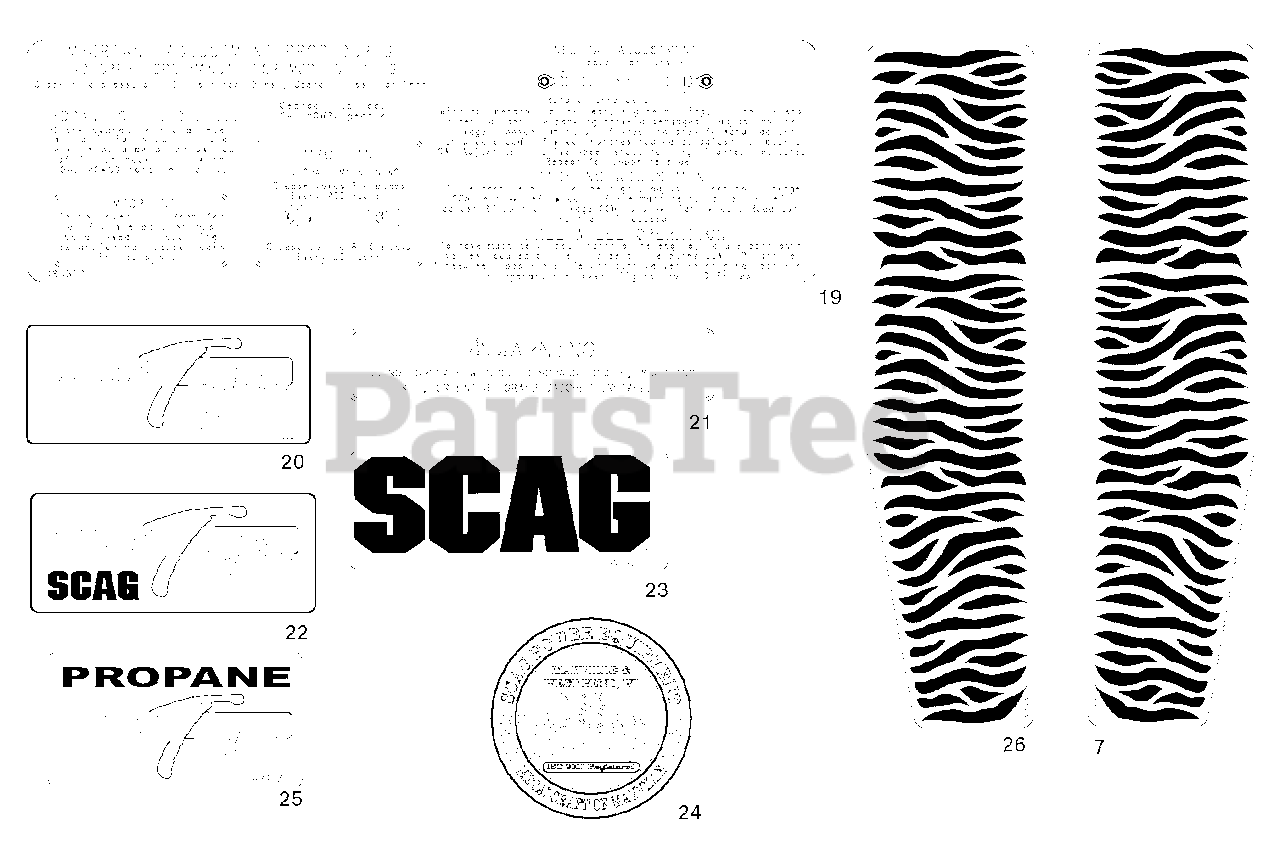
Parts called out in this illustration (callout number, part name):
7	Decal, Stripes-LH
19	Decal, STT Adjustments
20	Decal, Turf Tiger
21	Decal, Warning
22	Decal, Turf Tiger
23	Decal, Scag Logo
24	Decal, USA
25	Decal, Turf Tiger Propane
26	Decal, Stripes-RH
